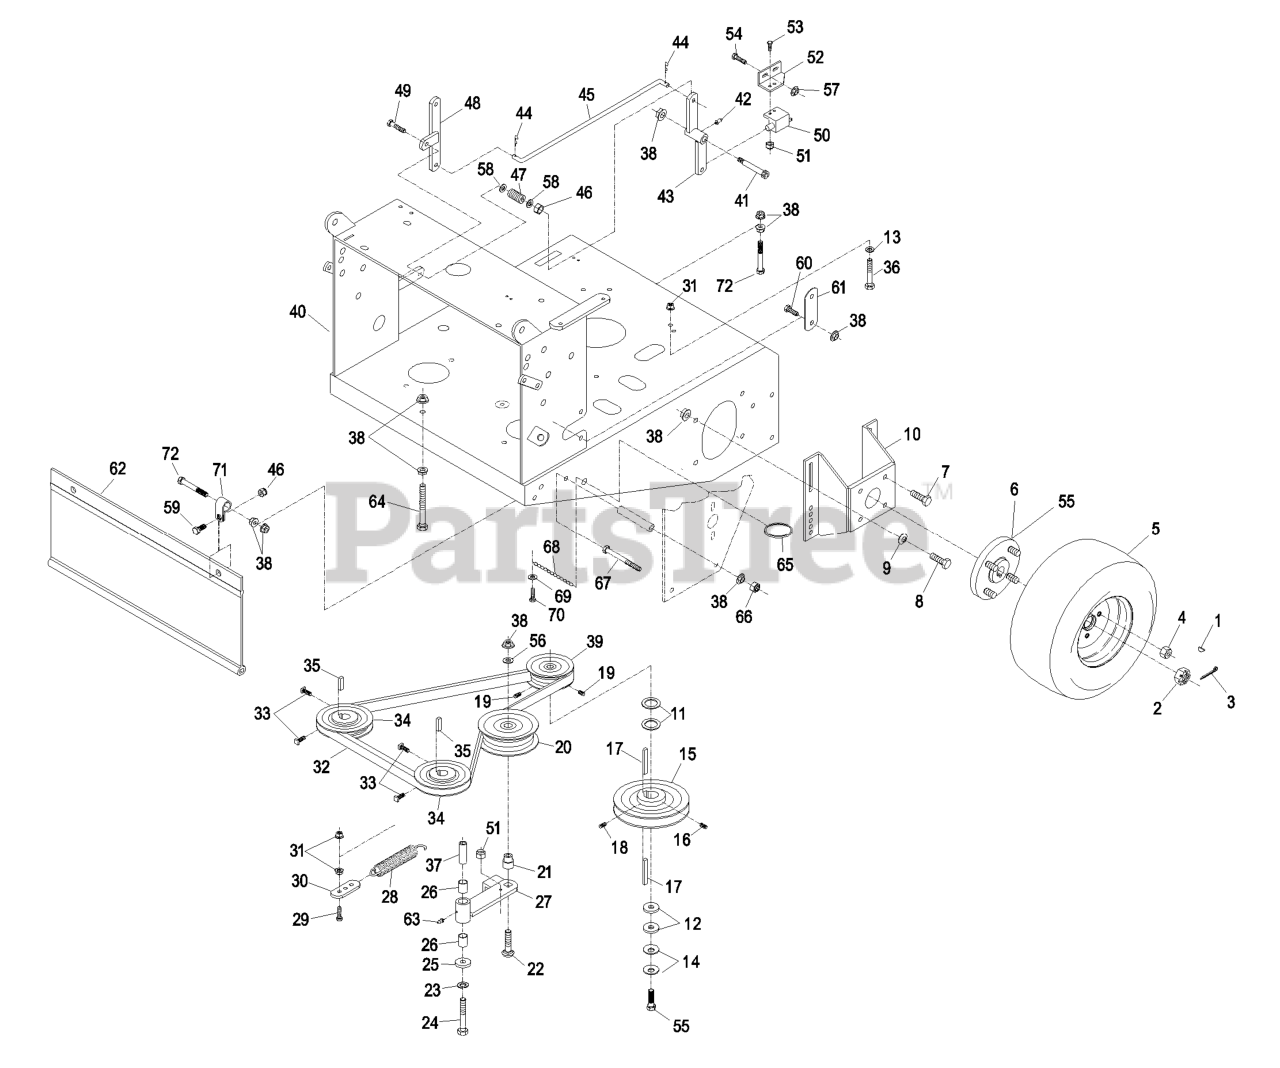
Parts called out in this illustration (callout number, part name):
1	KEY-WOODRUFF
3	PIN-COTTER
5	WHEEL AND TIRE ASM
10	MOUNT-MOTOR
11	WASHER-SPACER
13	WASHER-SPRING
14	WASHER-SPRING
18	SCREW-SET
19	SCREW-SET
21	BUSHING-IDLER
26	SLEEVE-BEARING
27	IDLER ARM ASM
28	SPRING-EXTENSION
30	ANCHOR-SPRING
33	SCREW-SET
34	SHEAVE ASM
37	BUSHING
43	BELLCRANK ASM
44	PIN-COTTER
45	LINKAGE-ENGAGE, BLADE
47	SPRING-COMPRESSION
50	SWITCH-OPEN, NORMALLY
52	BRACKET-SWITCH, BLADE
61	ARM-LIFT, DECK
65	RING-SPLIT
68	CHAIN-LINK, TWIST
70	SCREW-HSH
71	CLIP-LOOM
